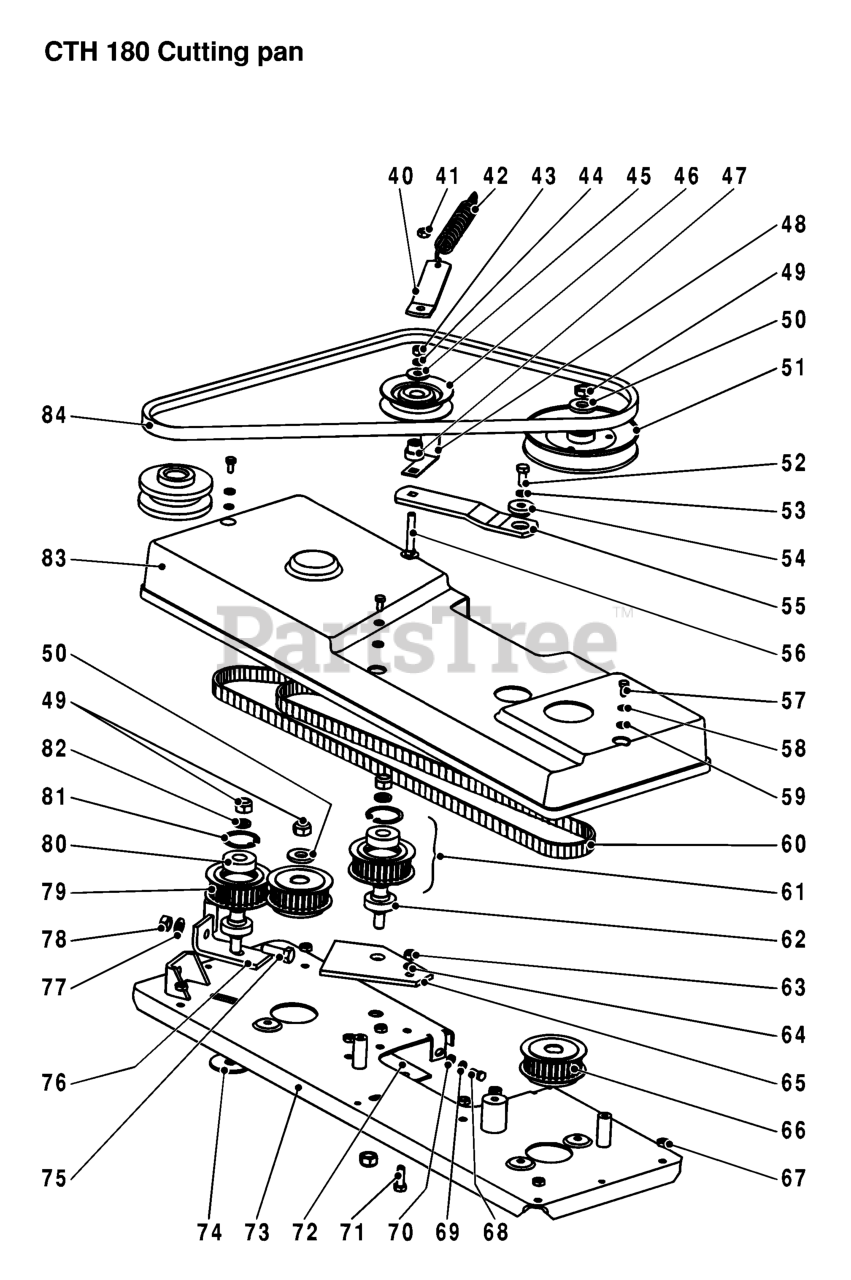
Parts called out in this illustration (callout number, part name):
41	NUT
44	SPRING WASHER
48	BELT GUIDE
53	SPRING WASHER
63	NUT
67	NUT
69	WASHER - M6
70	Blocking nut M 6 Z
77	WASHER
81	RETAINING RING
